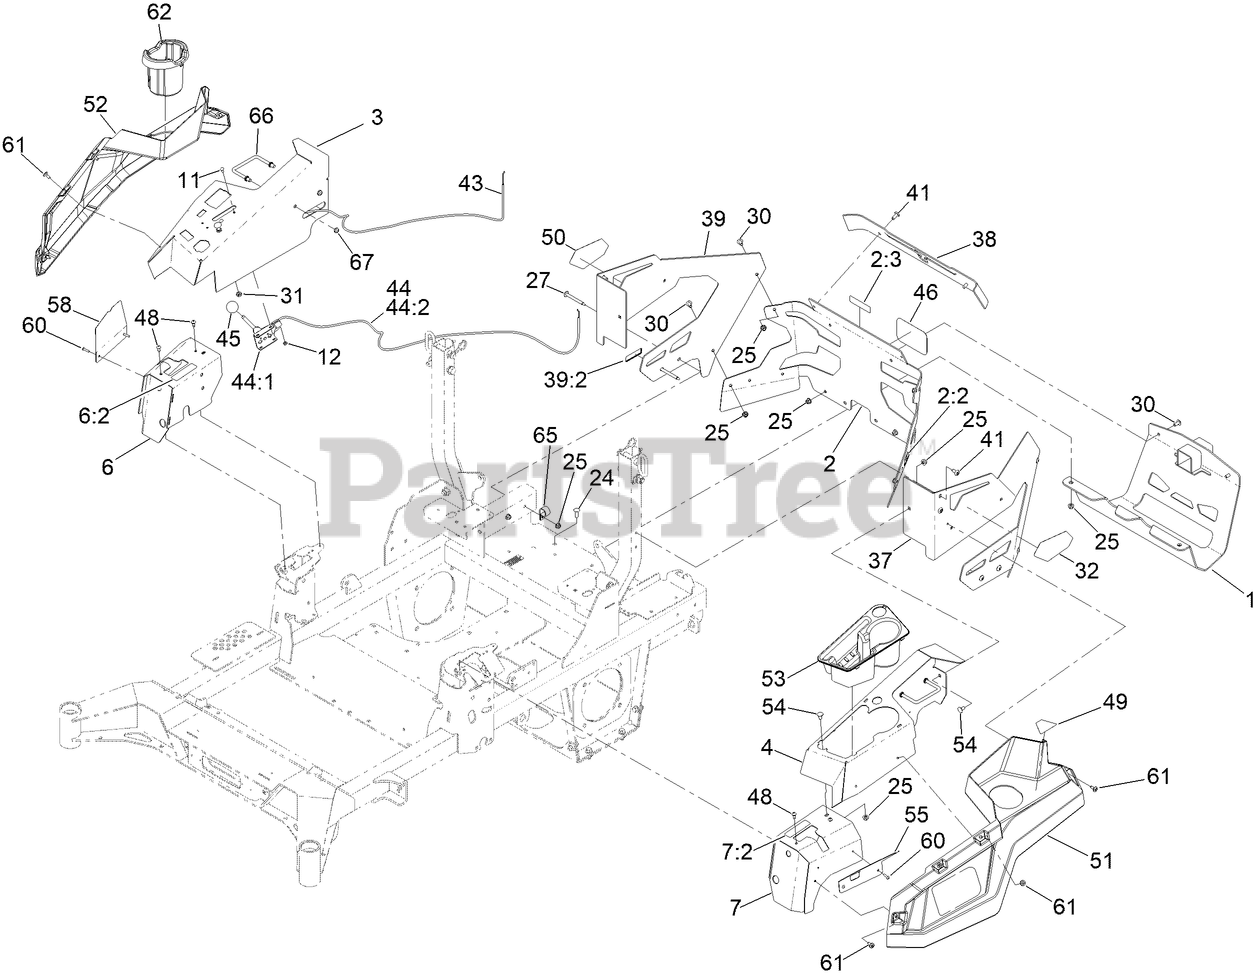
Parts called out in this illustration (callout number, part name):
1	MUFFLER GUARD ASM [BLACK]
2	REAR GUARD ASM
2:2	DECAL-WARNING
2:3	DECAL-HITCH
3	CONSOLE-RH
4	CONSOLE-LH
6	RH COVER ASM
6:2	DECAL-CONTROL, MOTION
7	LH COVER ASM
7:2	DECAL-CONTROL, MOTION
11	BOLT-CARR
12	NUT-LOCK, NI
24	SCREW-CARR
25	NUT-HF, NI
27	SCREW-TORX
30	SCREW-TORX
31	NUT-HJ
32	DECAL - 4000 SERIES, LH
37	GUARD-REAR, LH
38	GUARD-REAR, TOP
39	RH REAR GUARD ASM
39:2	DECAL-ARRESTOR, SPARK
43	CABLE-CHOKE CONTROL
44	THROTTLE CONTROL ASM
44:1	LEVER-THROTTLE
45	KNOB-BALL
48	SCREW-TPH THD FORM
49	DECAL-FILL, FUEL
50	DECAL-4000 SERIES, RH
51	SIDE POD, LH
52	SIDE POD, RH
53	CUP HOLDER
54	SCREW-CARR
55	PLATE-COVER, LH FRONT
58	PLATE-COVER, RH FRONT
60	RIVET-TRIFOLD
61	SCREW-SHOULDER
62	CUPHOLDER-RH
65	R-CLAMP
66	ROD-SUPPORT, POD
